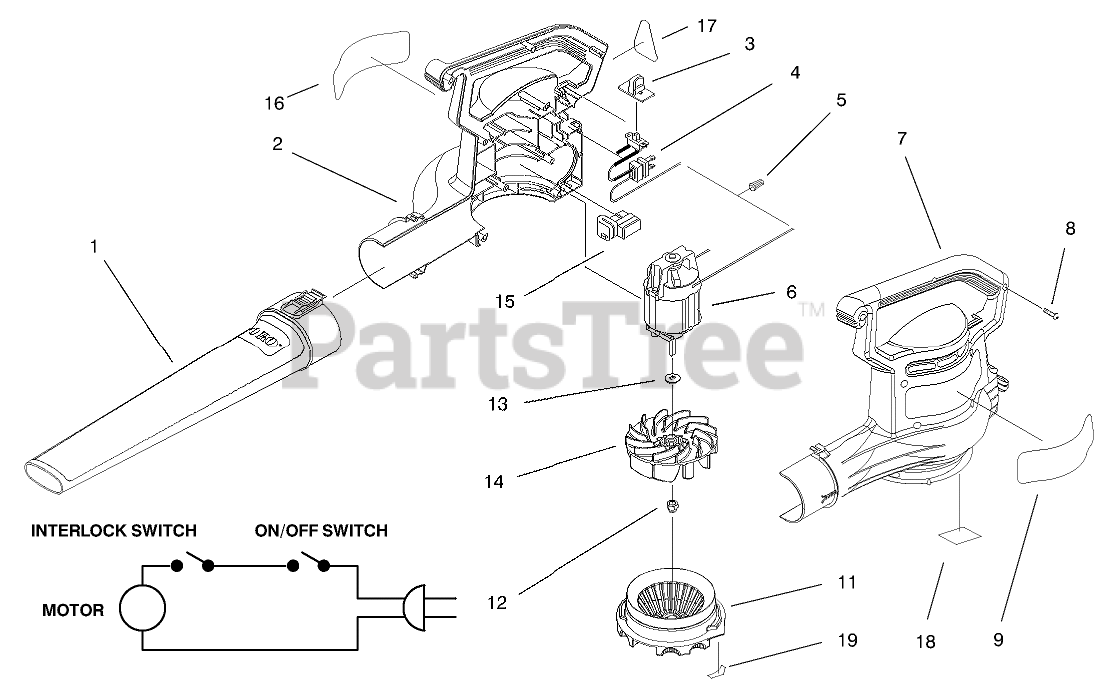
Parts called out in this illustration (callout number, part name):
1	TUBE-BLOWER LONG
2	Housing-RH
3	COVER-SWITCH
4	HARNESS ASSEMBLY
5	CONNECTOR-NUT, WIRE
6	MOTOR, ES-40, MID-BLOWER
7	HOUSING-LH
8	SCREW-PPH
9	DECAL-LOGO
11	Cover-Inlet
12	NUT-HEX
13	WASHER
14	IMPELLER - BLOWER
15	SWITCH - INTERLOCK
16	Decal-Warning
17	DECAL - INFORMATION
18	DECAL-ALIGNMENT, HOUSING
19	DECAL-ALIGNMENT, COVER
